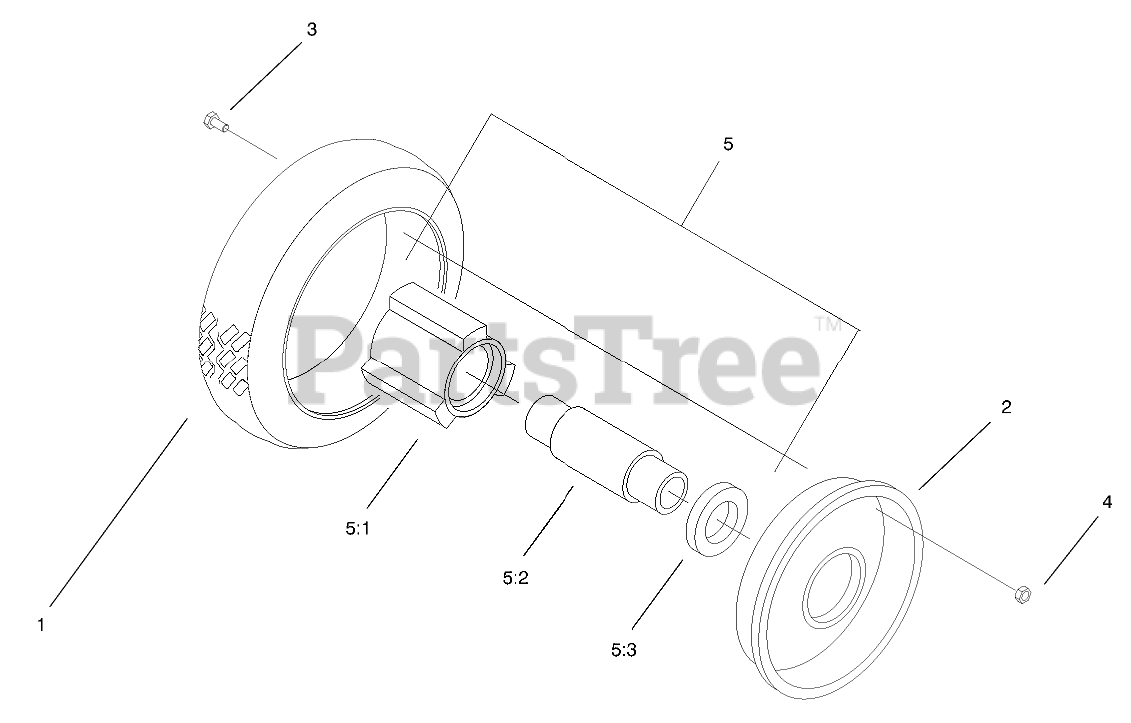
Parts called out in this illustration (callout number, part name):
2	PLATE-WHEEL, HALF
3	SCREW-HH
4	NUT-LOCK, NI
5	Hub & Brg ASM
5:1	HUB-BEARING
5:2	SPACER-BEARING
5:3	BEARING-WHEEL
